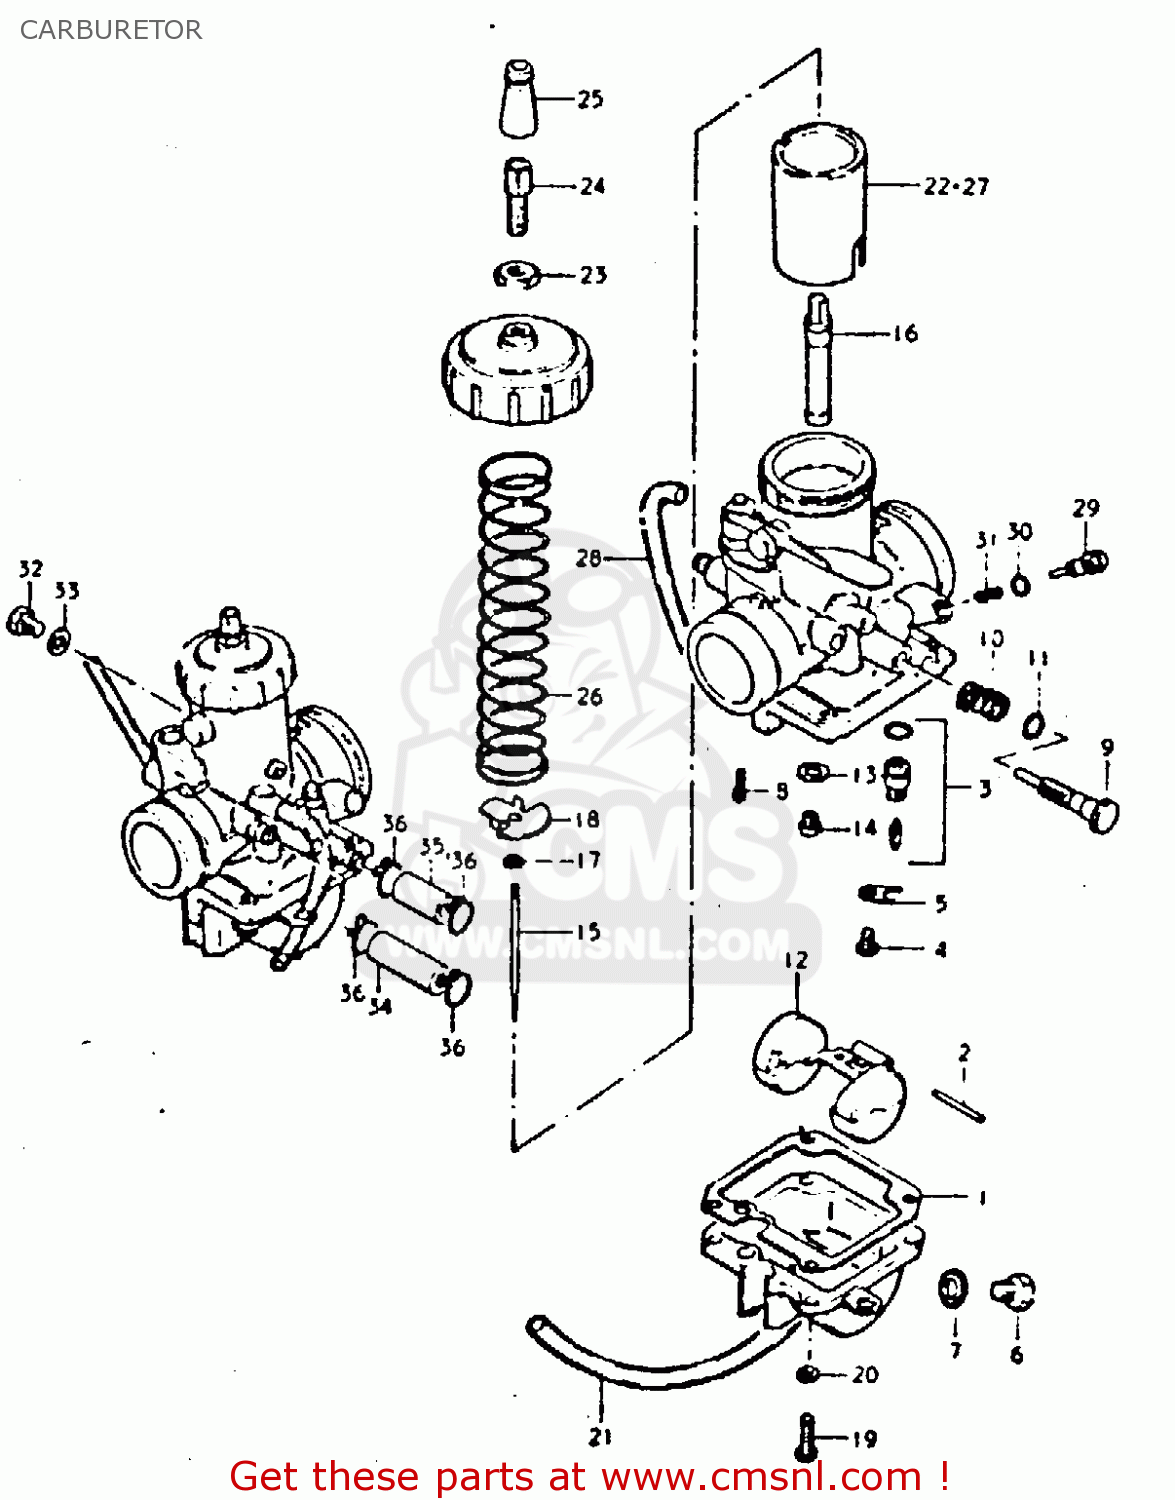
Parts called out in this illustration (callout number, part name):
1	GASKET,FLOAT CAHMBER (NAS)
2	PIN,FLOAT
3	VALVE ASSY,NEEDLE
4	SCREW
5	PLATE
6	PLUG
7	GASKET,DRAIN,PLUG (NAS)
8	JET
9	ADJUSTER
10	SPRING
11	O RING
12	FLOAT
13	WASHER
14	JET
15	NEEDLE,JET
16	JET, NEEDLE (0-1)
17	CLIP
18	PLATE,THROTTLE VALVE
19	SCREW
20	LOCK WASHER
21	HOSE
22	VALVE, THROTTLE LH (CA:2.0)
23	NUT
24	ADJUSTER,CABLE
25	CAP
26	SPRING,THROTTLE VALVE
27	VALVE, THROTTLE RH (CA:2.0)
28	HOSE
29	SCREW,PILOT AIR ADJUSTING
30	O RING
31	SPRING
32	BOLT
33	GASKET,THRO VALVE INSPECTION (NAS)
34	HOSE, STARTER
35	HOSE, FUEL
36	CLIP
